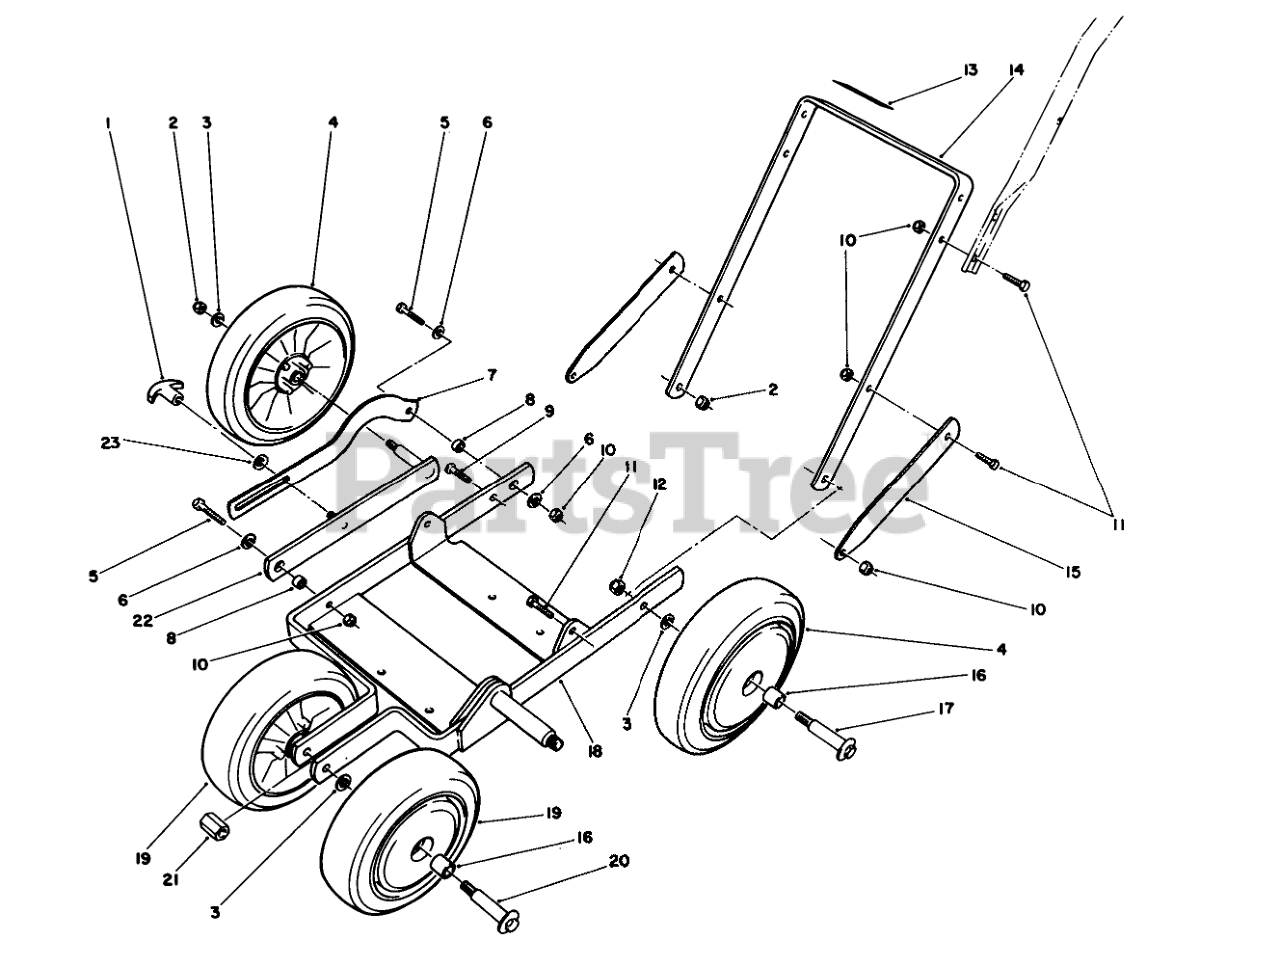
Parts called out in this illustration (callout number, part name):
2	NUT-LOCK
3	WASHER
4	Wheel & Tire Assembly (Incl. Ref. #16)
5	SCREW-HH
6	WASHER-FLAT
7	AXLE LINK
8	WHEEL MT BUSHING
9	3/8-24 X 1.00HEX BU. HD
10	NUT-LOCK, NI
11	SCREW-HH
12	NUT-HEX
13	Decal-Warning
14	LOWER HANDLE
15	SUPPORT HANDLE
16	BUSHING
17	WHEEL BOLT
18	Frame-Edger
19	Wheel & Tire Assembly (Incl. Ref. #16)
20	BOLT-WHEEL
21	HEX SPACER
22	WHEEL MOUNT WA
23	BELLEVILLE SPRING WASHE
